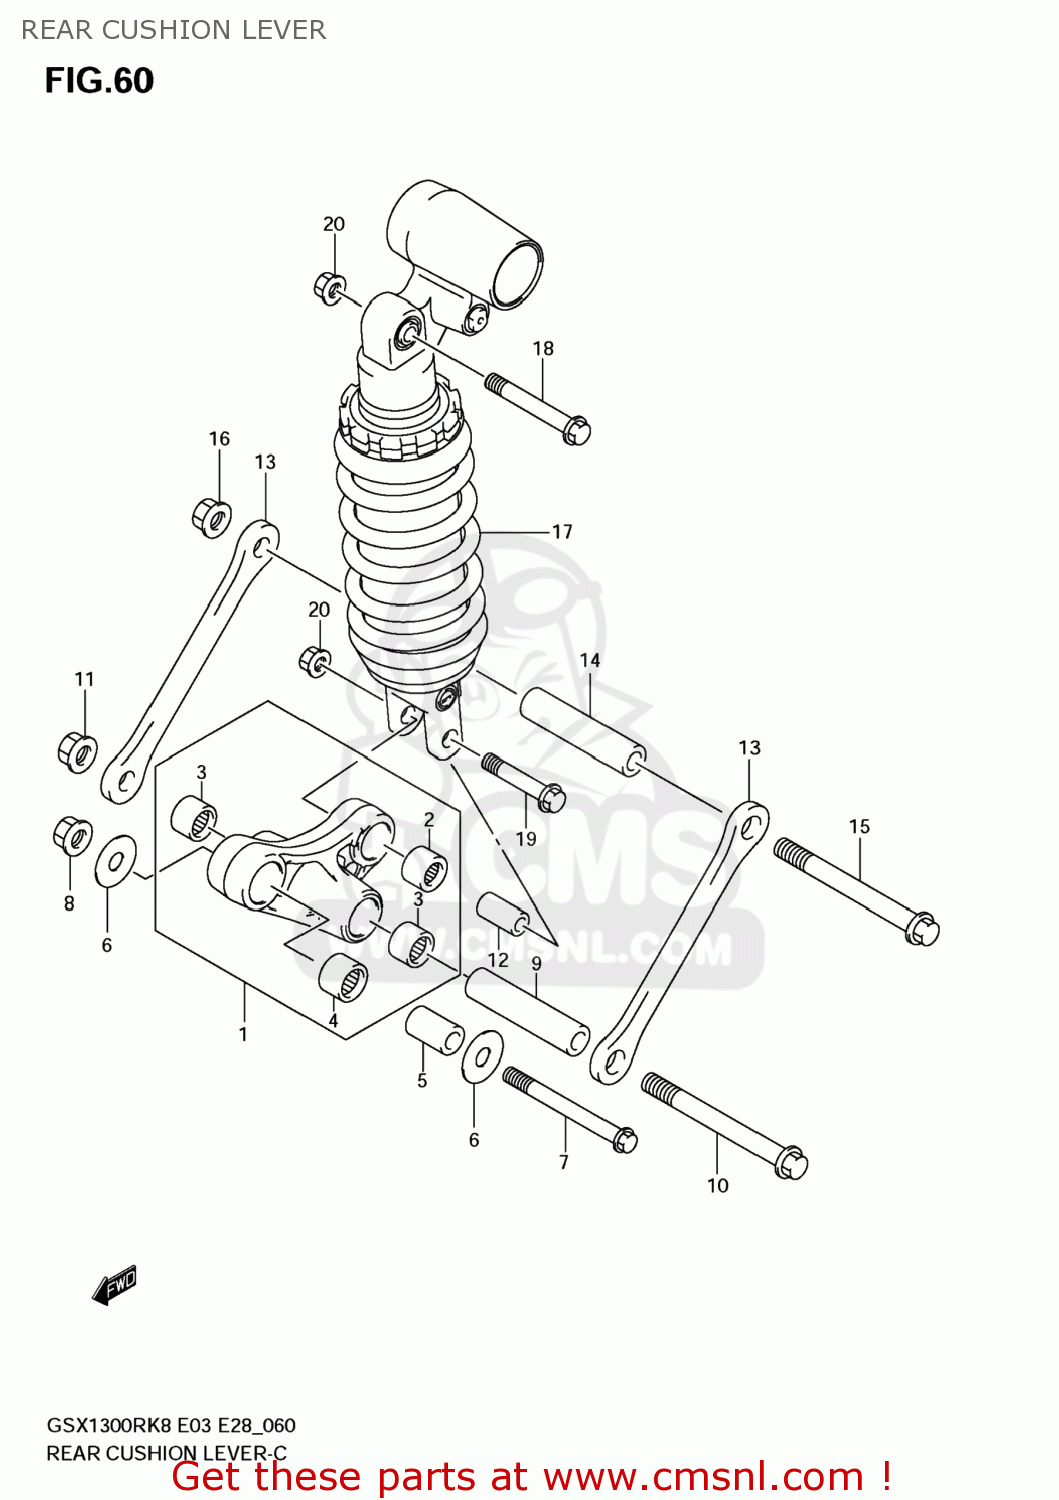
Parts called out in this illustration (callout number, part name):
1	LEVER SET,RR CUSHION
2	BEARING(20X27X30)
3	BEARING(17X24X25)
4	BEARING(17X24X26)
5	SPACER,RR CUSHION LEVER FR
6	WASHER
7	BOLT,RR CUSHION LEVER FR
8	NUT
9	SPACER,RR CUSHION LEVER CTR
10	BOLT,RR CUSHION LEVER CTR
11	NUT
12	SPACER,RR CUSHION LEVER
13	ROD,RR CUSHION
14	SPACER,RR CUSHION LEVER CTR
15	BOLT,RR CUSHION LEVER CTR
16	NUT
17	ABSORBER ASSY,RR SHOCK
18	BOLT(10X70)
19	BOLT(10X55)
20	NUT
